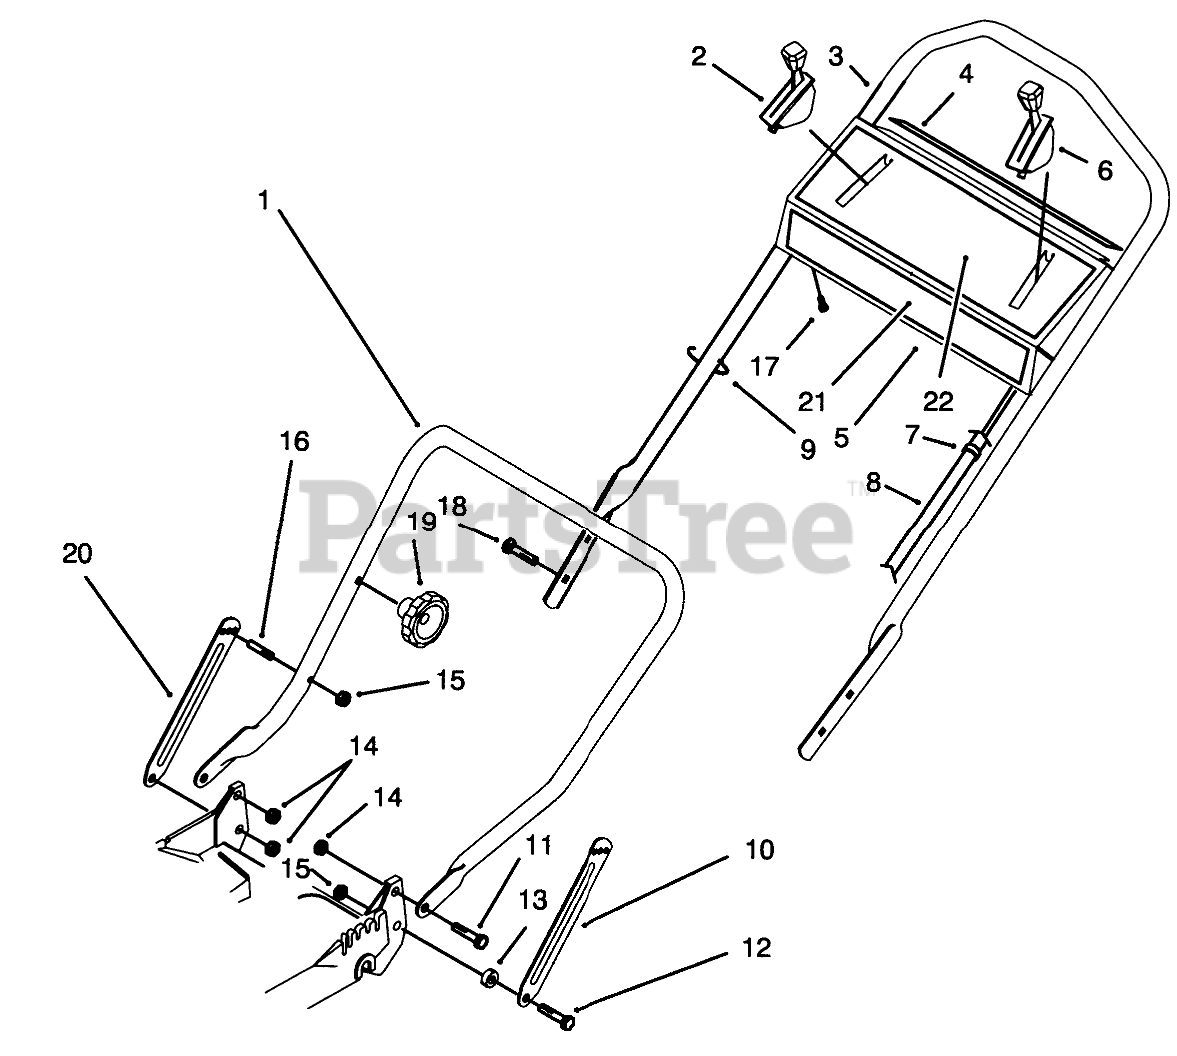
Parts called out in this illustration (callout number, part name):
1	LOWER HANDLE ASM
2	CONTROL-SPEED, GROUND
3	UPPER HANDLE, PVC DIP
4	DECAL - PANEL, REAR
5	Panel-Control (Incl. Ref. #4 & 22)
6	THROTTLE CONTROL
7	FITTING-RING
8	CONTROL CABLE COVER
9	TIE-CABLE
10	LH HANDLE LATCH
11	SCREW-SHOULDER
12	SCREW-SHOULDER
13	SPACER
14	NUT-LOCK, NI
15	NUT-LOCK, NI
16	HANDLE PIN
17	10-16X1/2 SHWH SCREW
18	5/16-18 X 2 HNDLE SCREW
20	RH HANDLE LATCH
21	DECAL - PANEL (TORO)
22	DECAL - INSTRUCTION
